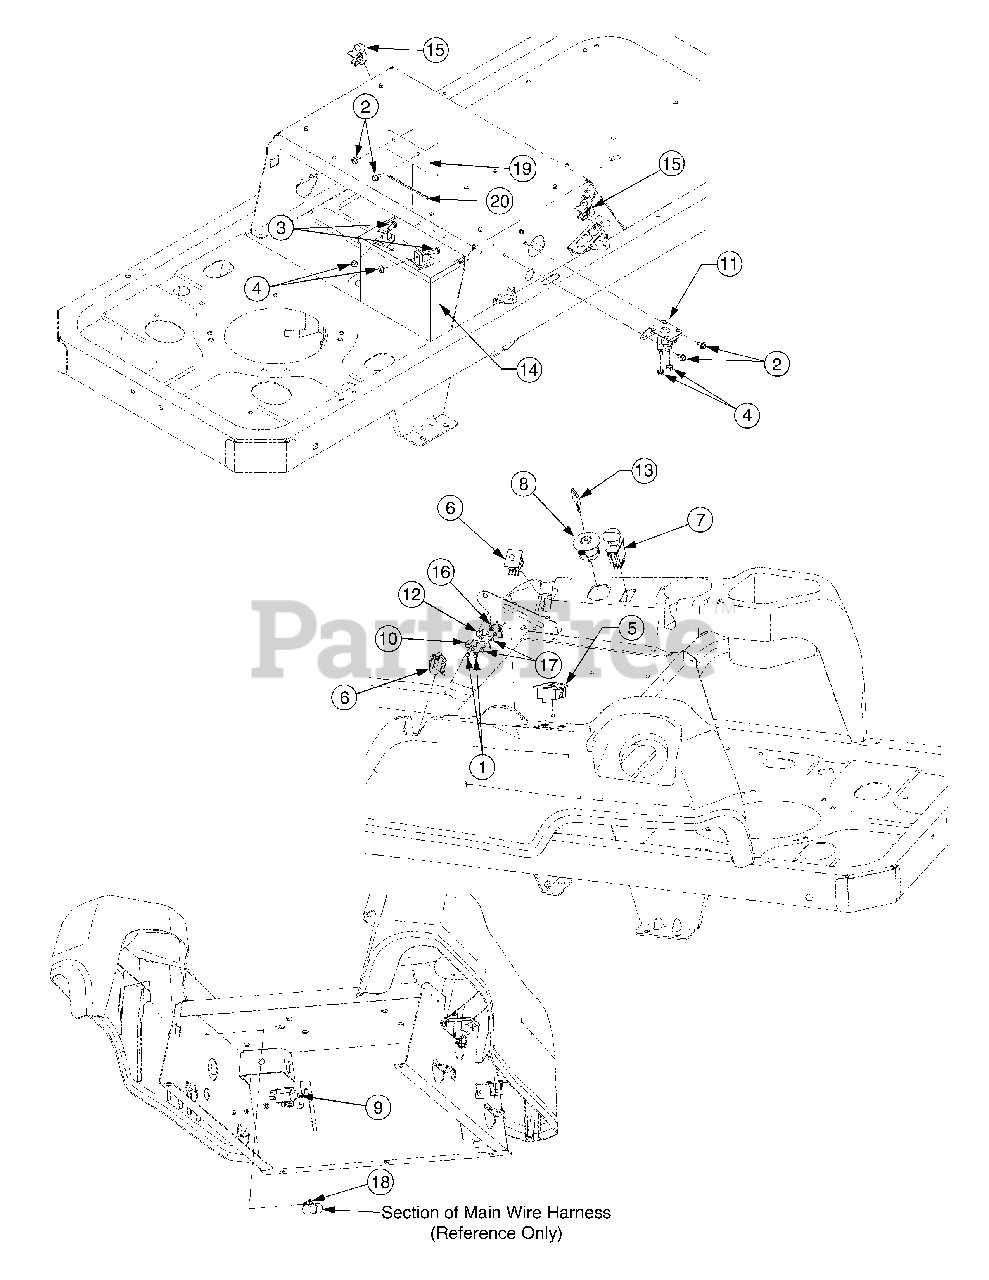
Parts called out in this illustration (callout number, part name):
1	Screw, Hex Wash. Hd. Tapp #8-18 x .5
2	Screw, Hex Wash. Hd. Tapp, 1/4-20 x .5
3	Screw, Hex Cap, 1/4-20 x .75 GR5 ..
4	Nut, Hex Sems, 1/4-20
5	Meter, Hour
6	Switch, Dbl. Pole - Neutral
7	Switch, PTO
8	Switch, Ignition
9	Switch, 3-Pole, (NC-NO-NO) - Brake
10	Switch, Outer Seat Spring
11	Solenoid
12	Switch, Inner Seat Spring
13	Key
14	Battery, 235 CCA
15	Switch, Snap Mount (N.C.) - Reverse
16	Plate, Insulator Boss
17	Plate, Insulator
18	Tie, Cable
20	Strip, Trim
